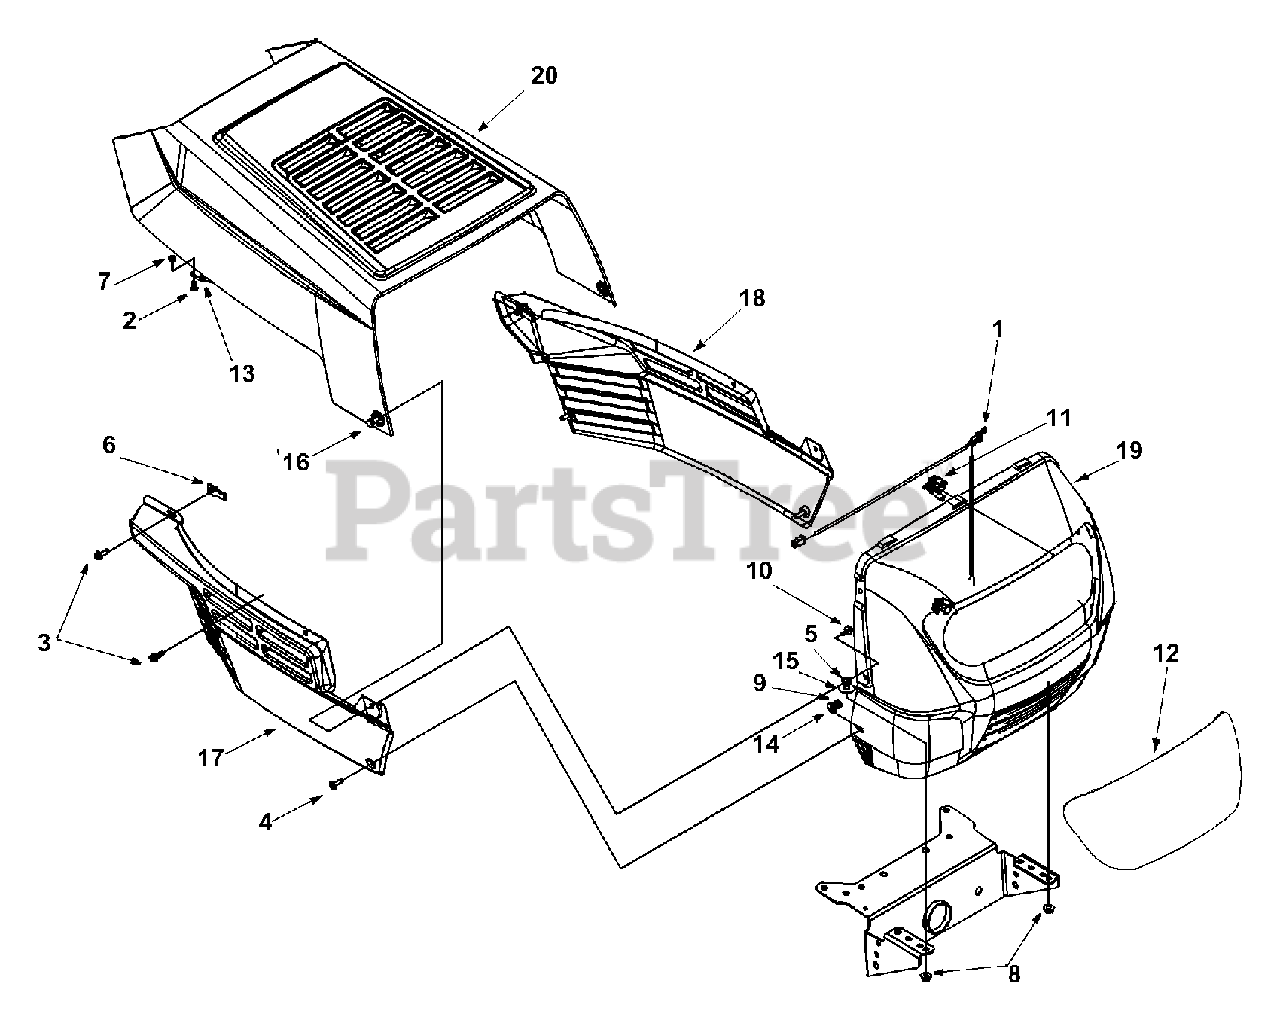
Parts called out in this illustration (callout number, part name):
1	Harness Assembly
2	Truss. Mach. Scr. #10-24 x 5" Lg.
3	Hex TT-Tap Scr. 1/4-20 x .75" Lg.
4	Pan Hd. Scr. 1/4-20 x .75" Lg.
5	Hex Bolt 5/16-18 x .75" Lg.
6	Speed Nut 1/4-20 Thd.
7	Hex Sems Nut 1-24 Thd.
8	Flange L-Nut 5/16-18 Thd.
9	Hex Nut 1/4-20 Thd.
10	Flange L-Nut 1/4-20 Thd.
11	Socket
12	Lens
13	Hood Latch
14	Bell-Wash. .265" I.D. x .75" O.D.
15	Fl-Wash. .349" I.D. x 1.0" O.D.
16	Shd. Scr. .375" I.D. x 1.25" O.D.
